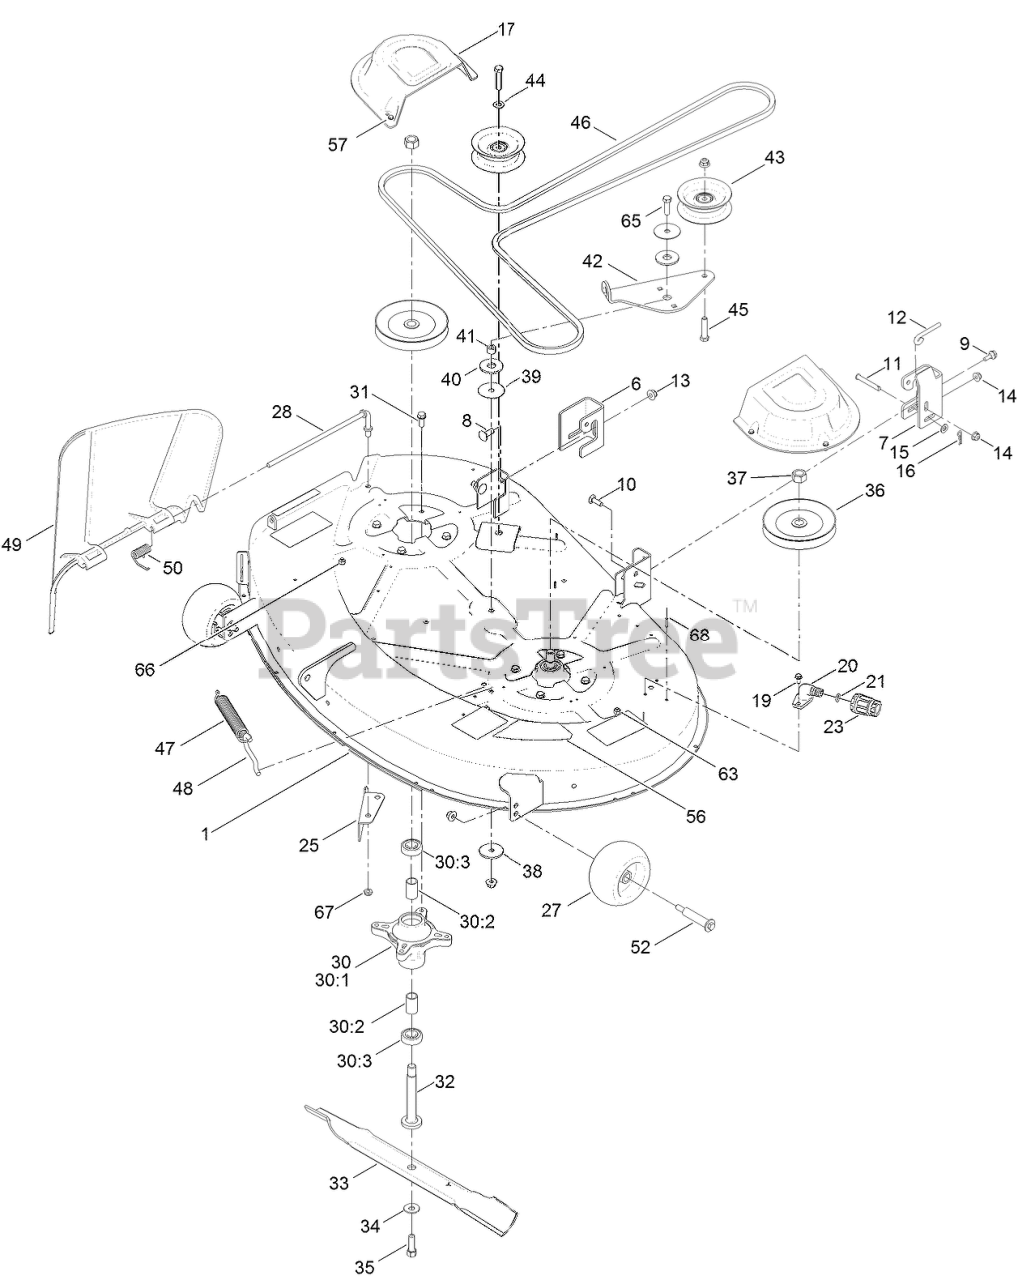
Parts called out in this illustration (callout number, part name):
1	42 INCH DECK AND DECAL ASM
6	BRACKET-HANGER, RH
7	BRACKET-HANGER, LH
8	BOLT-CARR
9	SCREW-SHOULDER, HHF
10	SCREW-CARR
11	PIN-CLEVIS
12	ROD-LEVEL, DECK
13	NUT-HF, NI
14	NUT-HF, NI
15	WASHER-PLAIN
16	PIN-COTTER
17	COVER-BELT
19	SCREW-HWH
20	FITTING-WASHOUT
21	O-RING
23	CONNECTOR-HOSE
25	BAFFLE-CUTOFF
27	ROLLER-SCALP, ANTI
28	ROD-PIVOT
30	SPINDLE ASM
30:1	SPINDLE
30:2	SPACER
30:3	BEARING-BALL
31	SCREW-TAPTITE
32	SHAFT-SPINDLE
33	BLADE-HIGH LIFT
34	WASHER-BELLEVILLE
35	SCREW-HH
36	Pulley
37	NUT-HEX
38	WASHER-REBOUND
39	WASHER
40	WASHER-FRICTION, COMPOSITE
41	SPACER
42	ARM-IDLER
43	PULLEY-IDLER, FLAT
44	WASHER-FLAT
45	SCREW-HH
46	V-BELT
47	SPRING-EXTENSION
48	HOOK-RETURN, SPRING
49	DEFLECTOR
50	SPRING-TORSION
52	BOLT-SHOULDER
57	SCREW-TAPTITE
63	NUT-LOCK, NI
65	SCREW-HH
66	SCREW-HH
67	NUT-LOCK, NI
68	RIVET-BLIND
